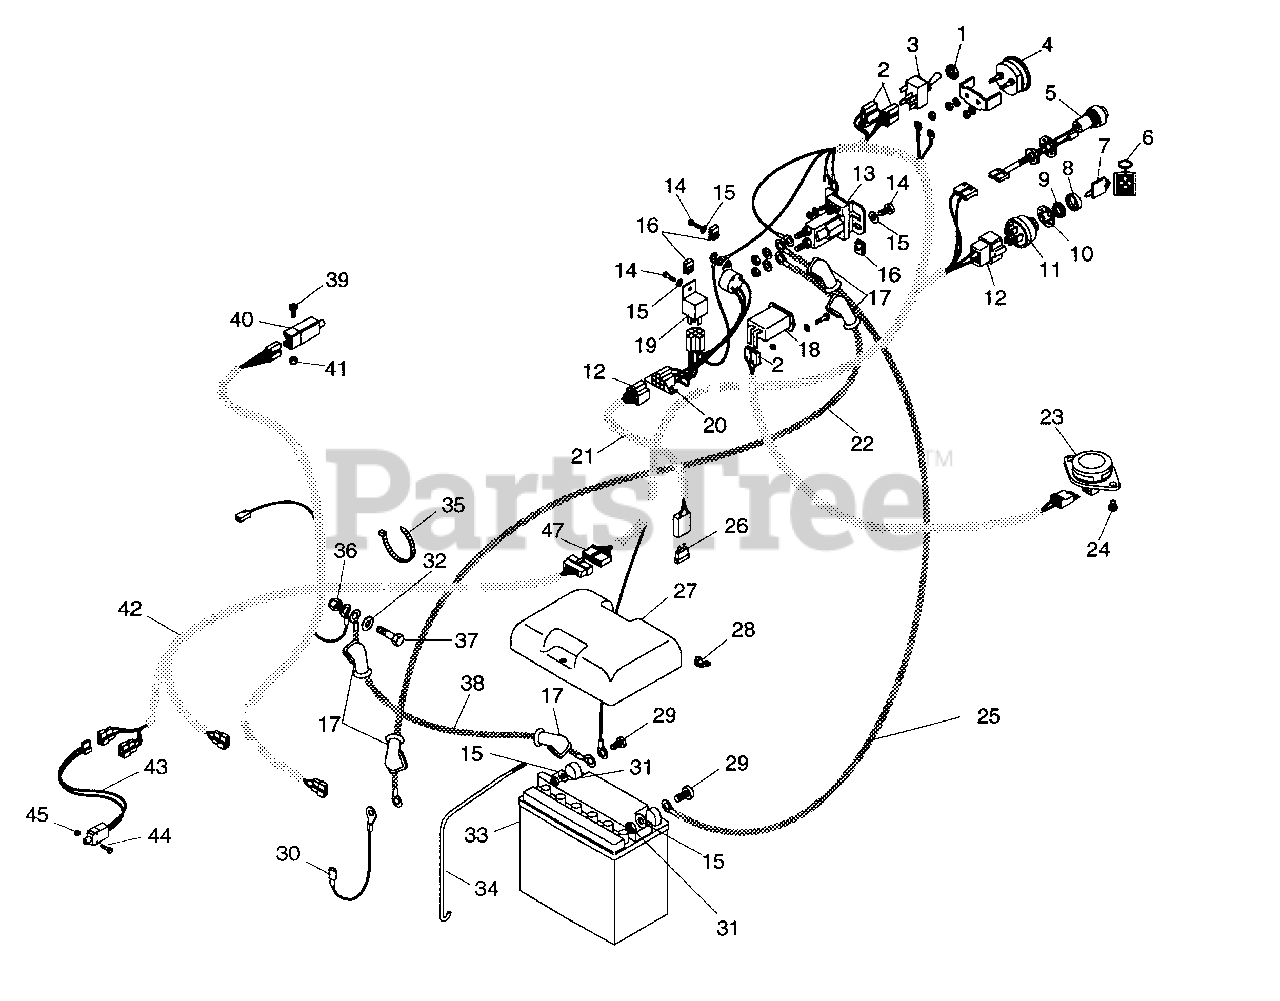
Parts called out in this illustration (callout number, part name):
1	Nut .50-27
2	Terminal
3	Switch Assembly
4	Gauge - Ammeter
5	Light Indicator
6	Key Chain
7	Ignition Switch Key
8	Cap-Ignition Switch
9	Nut-Panel .562-24 Greco
10	Washer-Lock-Internal .563 x .040
11	Ignition Switch
12	Connector
13	Solenoid
14	Screw-Machine .25-20
15	Washer-Flat-Steel .281 x .620 x .065
16	Nut-Speed .25-20
17	Boot, Insulator
18	Hour Meter
19	Relay
20	Module, Time Delay
21	Harness, Wiring
22	Assembly, Cable Electrical
22	Cable, Battery to Solenoid
23	Seat Switch
24	Screw-Machine .25-20 x .50
25	Cable, Starter
26	Fuse, 25 Amp
27	Cover, Battery
28	Nut-Wing .250-20
29	Bolt-Hex .25-20 x .75 Grade 5
30	Assembly, Cable
31	Nut-Hex .250-20
32	Washer-Flat-Steel .344 x .688 x .065
33	Battery
34	Rod, Battery
35	Tie, Wrap, Black
36	Nut-Locking-Nylon .312-18
37	Bolt-Hex .31-18 x 1.00 Grade 5
38	Cable, Negative Battery
39	Screw-Machine 10-24 x .625
40	Switch, Interlock
41	Nut-Locking 10-24
42	Harness, Wiring
43	Switch
44	Screw-Machine 6-32 x .875
45	Nut-Locking-Machine 6-32
46	Connector, Female
